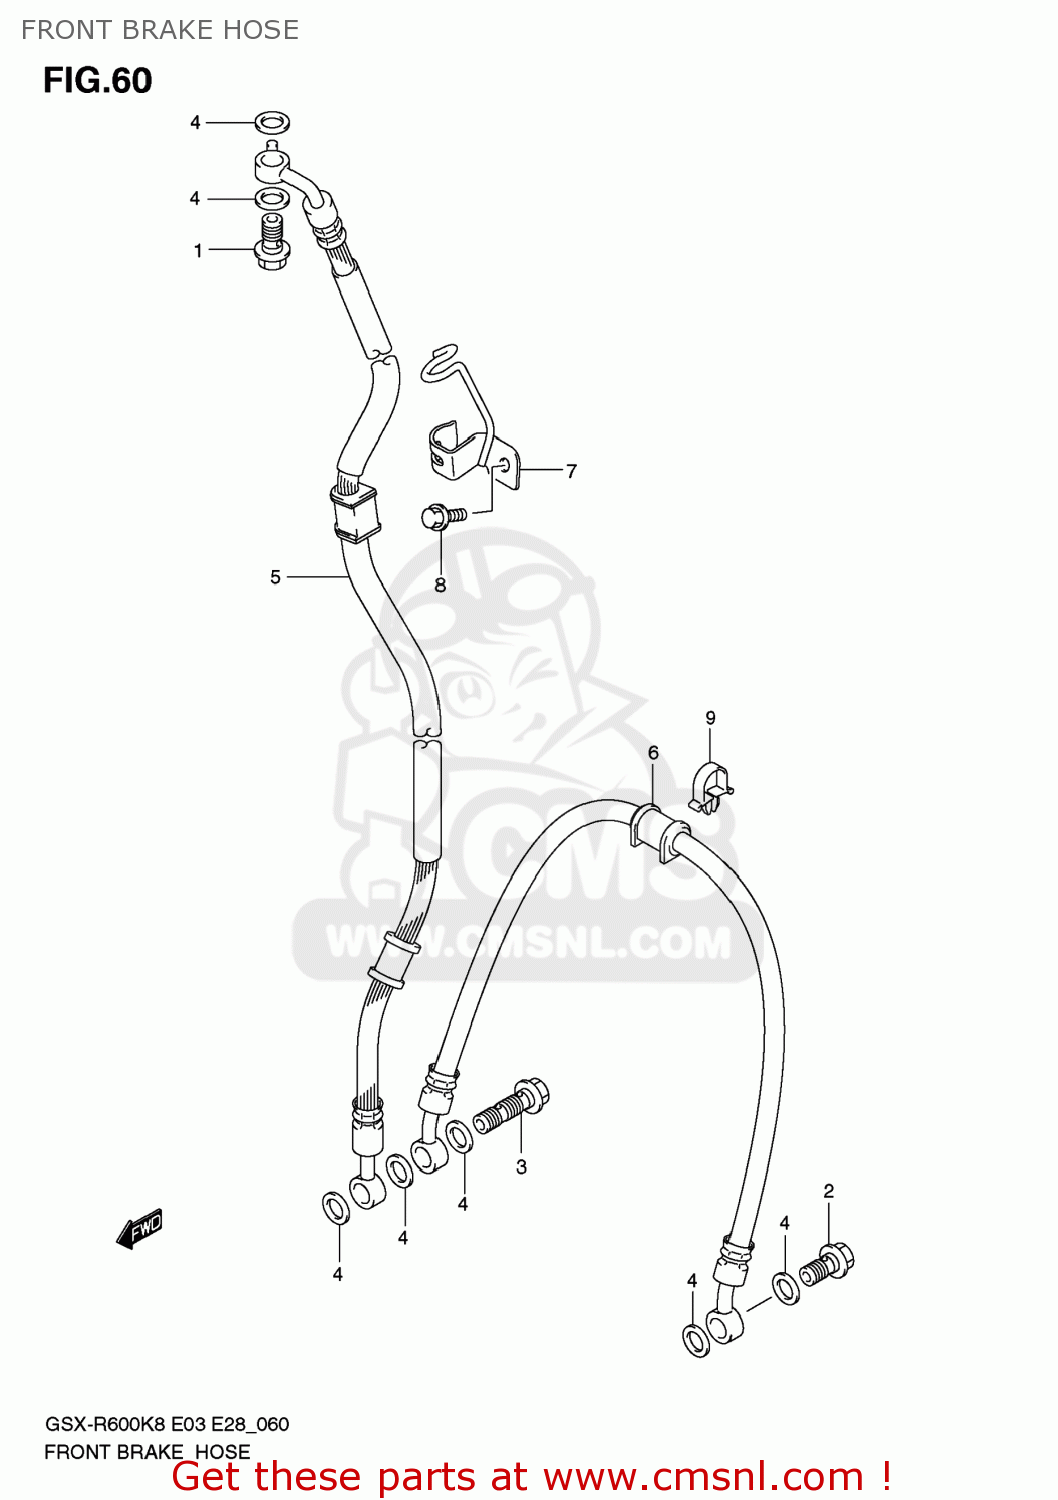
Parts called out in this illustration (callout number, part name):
1	BOLT UNION
2	BOLT UNION
3	BOLT UNION
4	WASHER(10X15X1.5)
5	HOSE,FR BRAKE NO.1
6	HOSE,FR BRAKE NO.2
7	CLAMP,FR BRAKE HOSE NO.1
8	BOLT
9	CLAMP
